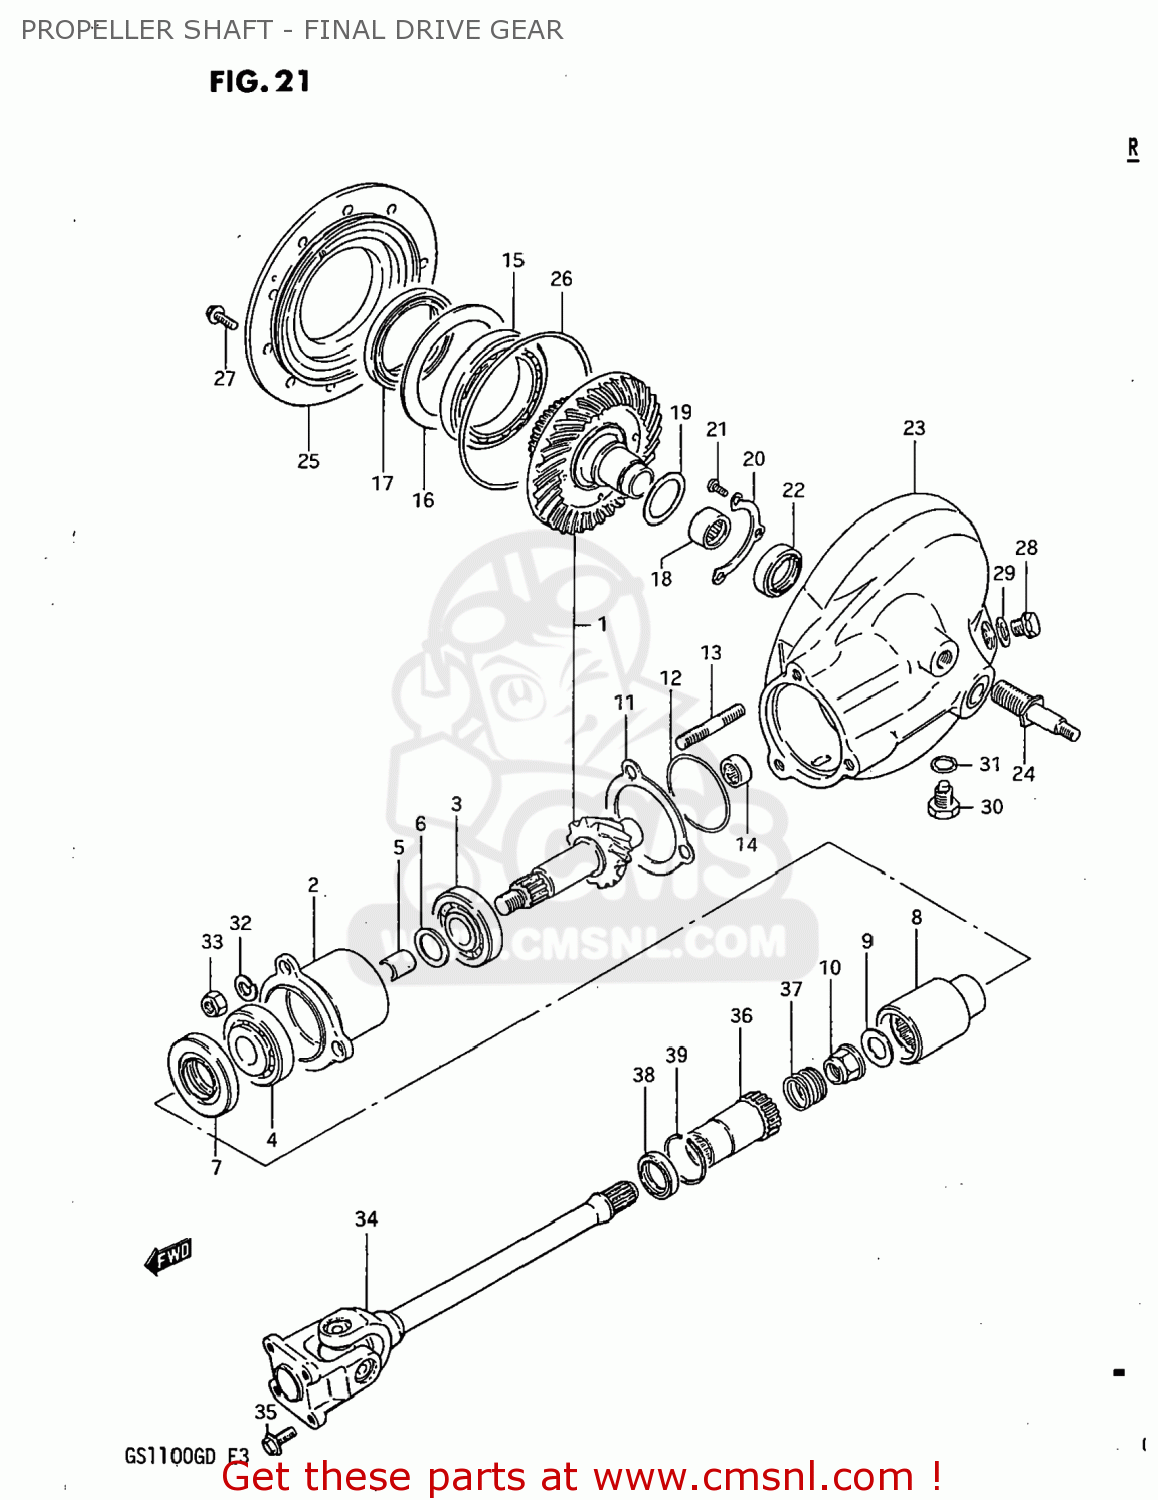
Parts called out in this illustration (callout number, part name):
1	GEAR SET,FINAL BEVEL
2	HOUSING,DRIVE GEAR
3	BEARING(25X52X19.25)
4	BEARING
5	SPACER (25.2X30X3.5)
6	SHIM (25X30X2
7	SEAL,OIL(32X54X7)
8	GEAR,FINAL DRIVE
9	WASHER(14X29X4)
10	NUT
11	SHIM,DRIVE GEAR HOUSING
12	O RING(D:2.4,ID:62.6)
13	STUD 10X30
14	BEARING(24X33X17)
15	BEARING(70X110X13)
16	SHIM,DRIVEN GEAR BEARING
17	SEAL,OIL(70X96X16)
18	BEARING(35X48X23.7)
19	SHIM,FINAL DRIVEN GEAR
20	RETAINER,FINAL DRIVEN GEAR BRG
21	SCREW 6X12
22	SEAL,OIL(30X42X7)
23	CASE ASSEMBLY,FINAL GEAR
24	STUD
25	CASE,FINAL GEAR BEARING
26	O-RING (D:3.1 ID:144.4)
27	BOLT
28	PLUG (14X12)
29	GASKET(14X19.2X2) (NAS)
30	PLUG
31	GASKET(14X19.2X2) (NAS)
32	LOCK WASHER
33	NUT
34	SHAFT ASSEMBLY,PROPELLER
35	BOLT(8X17)
36	COUPLING,PROPELLER SHAFT
37	SPRING
38	SEAL,OIL(30X40.5X5.5)
39	CIRCLIP
